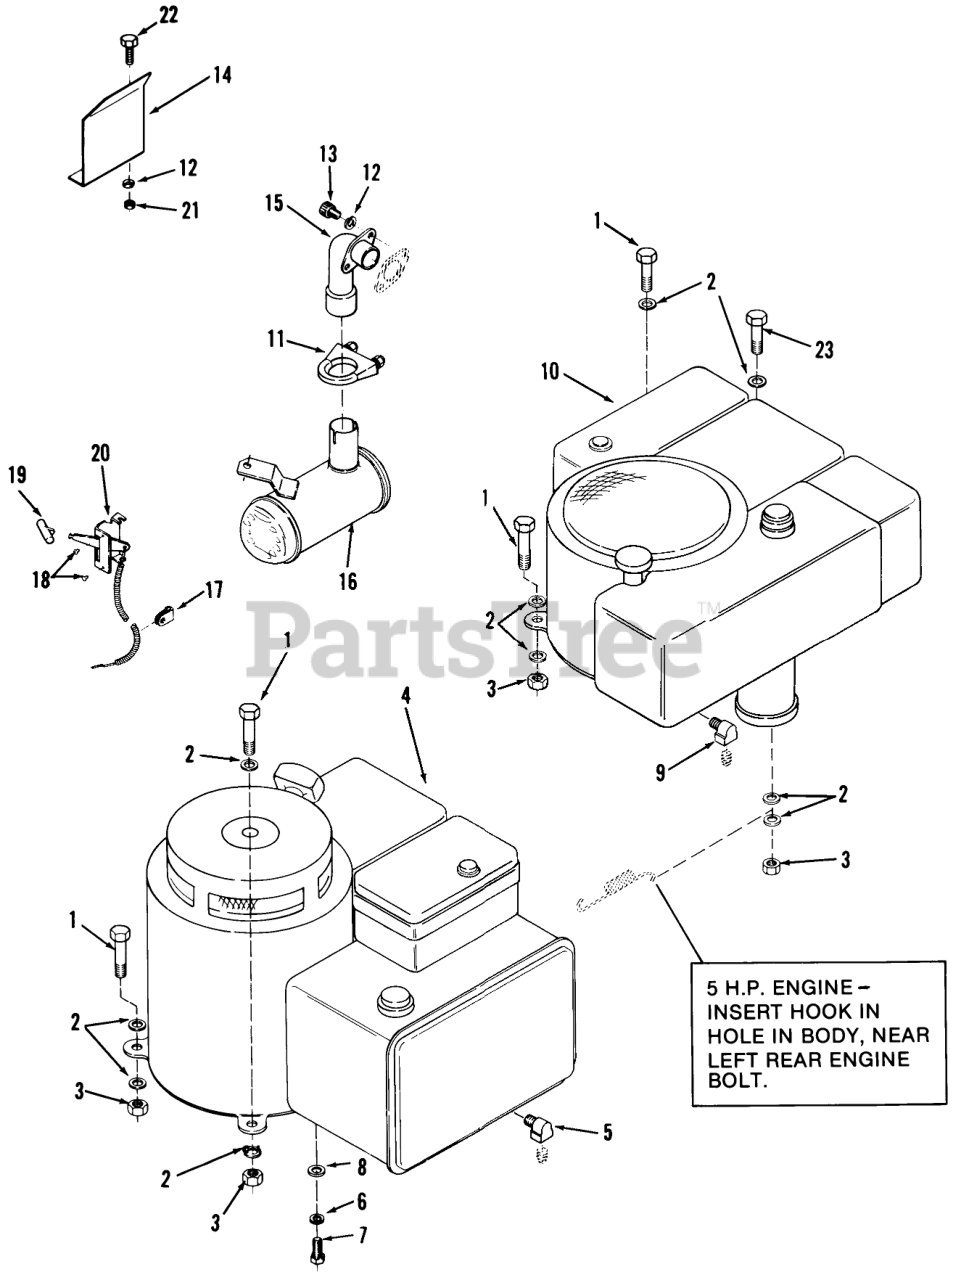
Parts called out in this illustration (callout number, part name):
2	WASHER 5/16 SAE
2	WASHER
4	Engine 5 H.P.-B S Model 130902 Type 0584-01
5	Street Elbow
10	Engine 8 H.P.-B S Model 191707 Type 5663-01 A-81 Only
10	Engine 11 H.P.-B S Model 252707 Type 0207-01 A-111 Only
10	Engine 8 H.P.-B S Model 191702 Type 5648-01 A-81R Only
13	SHCS 5/16-18X.625
17	THROTTLE CONTROL CLP
18	RIVET
